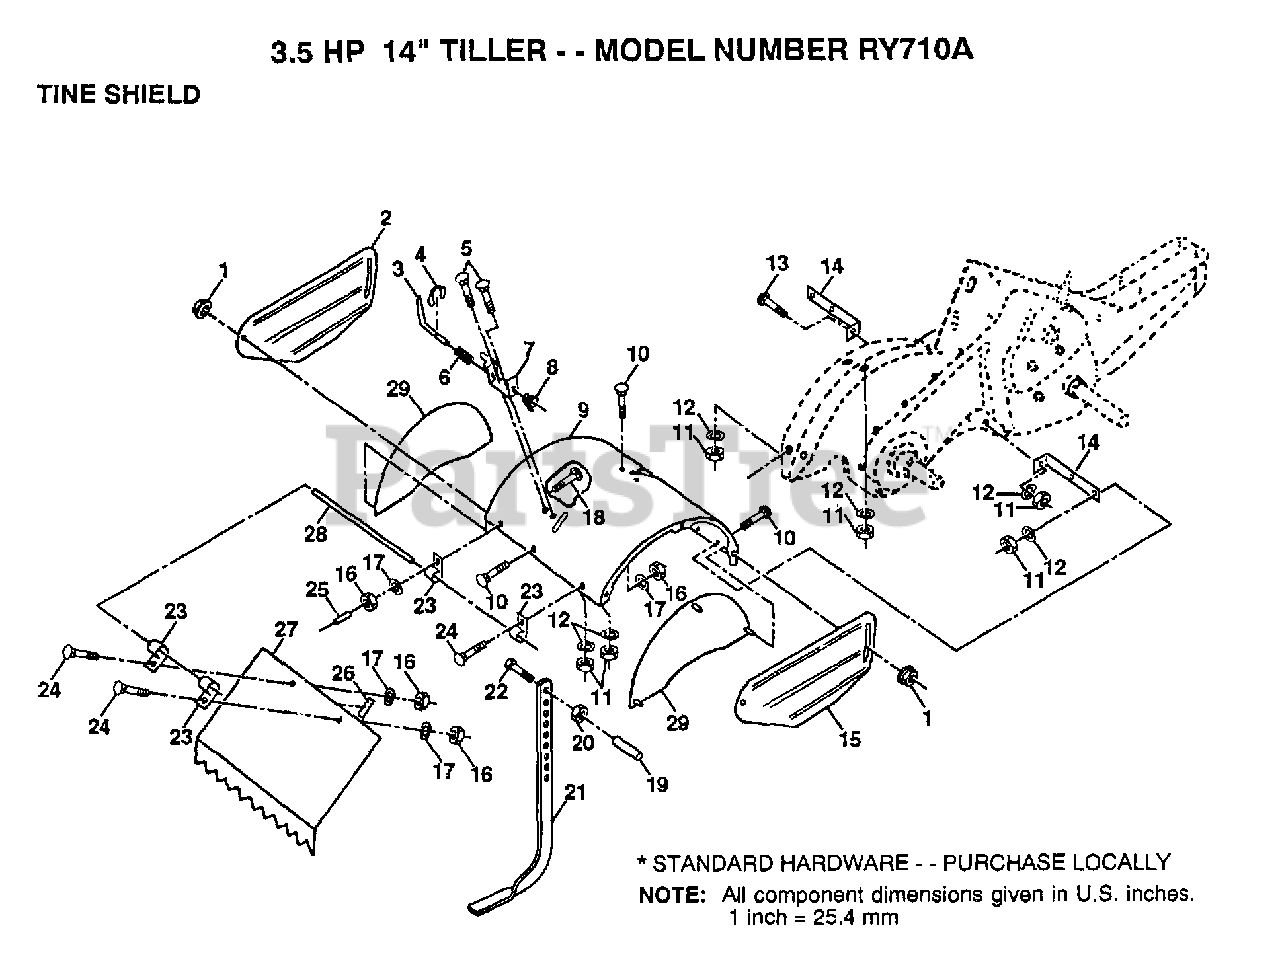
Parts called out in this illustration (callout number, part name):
1	NUT
2	SHIELD.SD.OUT.LH
3	STAKE PIN TI
4	KLIP RING TI
5	BOLT CRT
6	SPRING TI
7	LATCH BRACKET TI
8	SPRING CRT
10	BOLT
11	NUT.HEX.5/16-18
12	LOCKWASHER
13	BOLT
14	BRKT SHIELD TINE
15	SHIELD.SD.OUT.RH
17	LOCKWASHER
18	BOLT
19	GRIP CRT
20	NUT.HEX.3/8-16UNC
22	BOLT
23	HINGE CRT
24	BOLT
25	VINYL CAP TI
26	PAD IDLER TI
27	SHIELD LEVELING
28	PIN HINGE
29	"SHIELD, SIDE"
